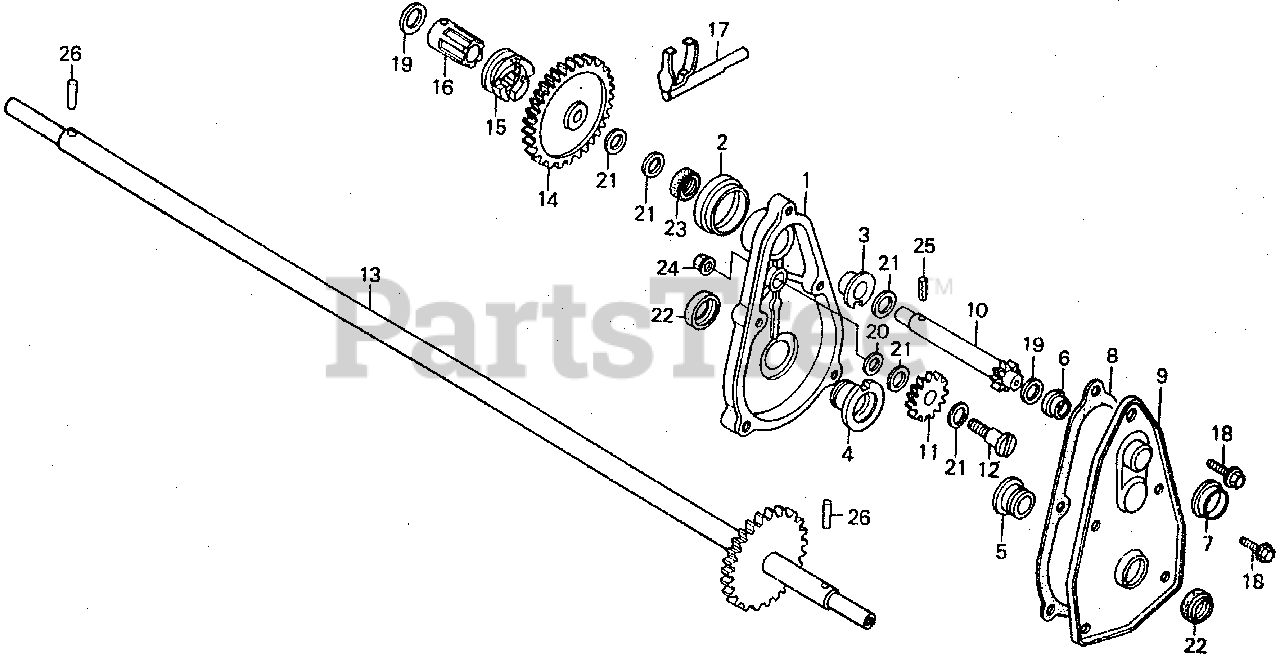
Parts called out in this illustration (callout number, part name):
1	CASE, REDUCTION
3	BUSH, FIRST GEAR (NOT AVAILABLE)
4	BUSH, CASE SIDE (NOT AVAILABLE)
5	BUSH, COVER SIDE (NOT AVAILABLE)
6	BUSH, L. REDUCTION COVER (NOT AVAILABLE)
7	BUSH, CASE SUPPORT
8	GASKET, REDUCTION CASE (NOT AVAILABLE)
9	COVER, REDUCTION CASE
10	SHAFT, FIRST GEAR (NOT AVAILABLE)
11	GEAR, IDLE (NOT AVAILABLE)
12	SHAFT, IDLE GEAR (NOT AVAILABLE)
13	SHAFT, FINAL
14	GEAR, DRIVEN
15	CLUTCH, DRIVEN
16	SHAFT, CLUTCH
17	SHAFT, SHIFT
18	BOLT, FLANGE (6X12) (CT200)
19	WASHER, THRUST (10MM)
20	WASHER (8MM) (NOT AVAILABLE)
21	WASHER, THRUST (12MM)
23	OIL SEAL (NOT AVAILABLE)
24	NUT, FLANGE (8MM)
25	PIN, SPRING (5X18)
26	ROLLER (6X22.4)
